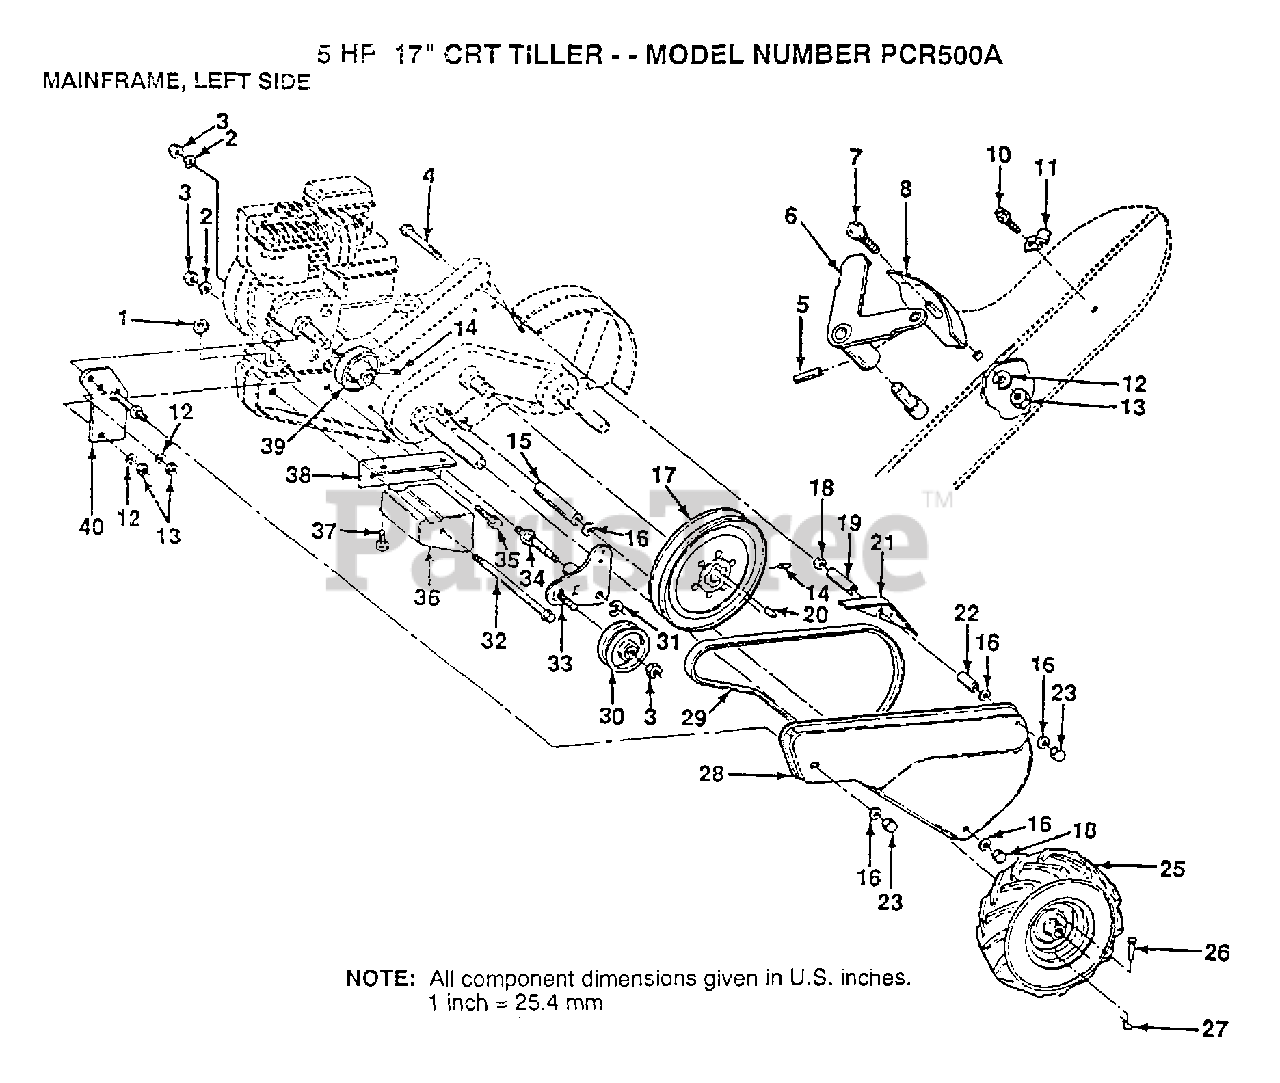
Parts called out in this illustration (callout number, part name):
2	LOCKWASHER
3	NUT.HEX.3/8-16UNC
4	BOLT-HEX TI
6	LEVER ASM CRT
7	BOLT
8	PANEL TI
11	CONDIUT CLIP T
12	LOCKWASHER
14	SET SCREW
15	SPACER
16	WASHER
17	"SHEAVE 10"" CRT"
18	NUT.HEX.5/16-18
19	SPACER CRT
20	KEY T
21	GUARD CRT
22	SPACER CRT
23	NUT TI
25	TIRE.CHV.13X5.0-6
26	RIVET.DRILL.1.75
27	RETAINER M
30	PULLEY-IDLER TI
31	KLIP RING
32	BOLT CRT
34	SHIFT ARM CRT
35	BOLT
36	COUNTERWEIGHT CRT
37	BOLT.HEX.5/16-1.5
38	BRACKET LH CRT
40	BRACKET ASSY CRT
